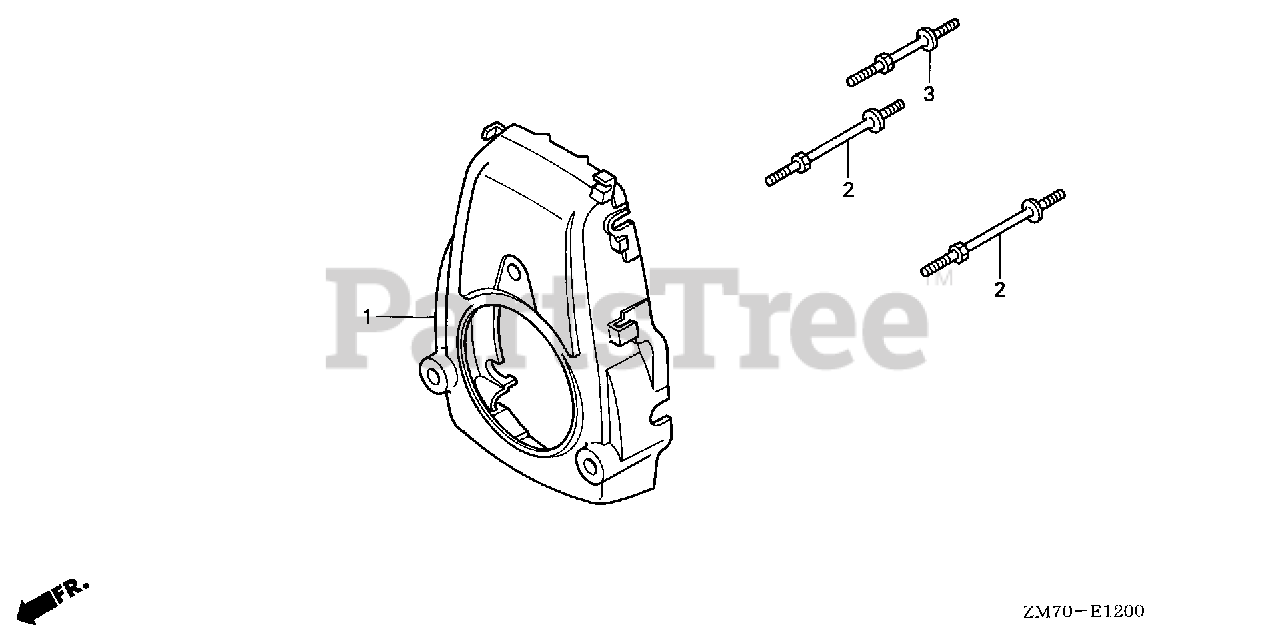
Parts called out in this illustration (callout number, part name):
1	COVER, FAN *R280* (POWER RED)
2	BOLT A, STUD
3	BOLT B, STUD
